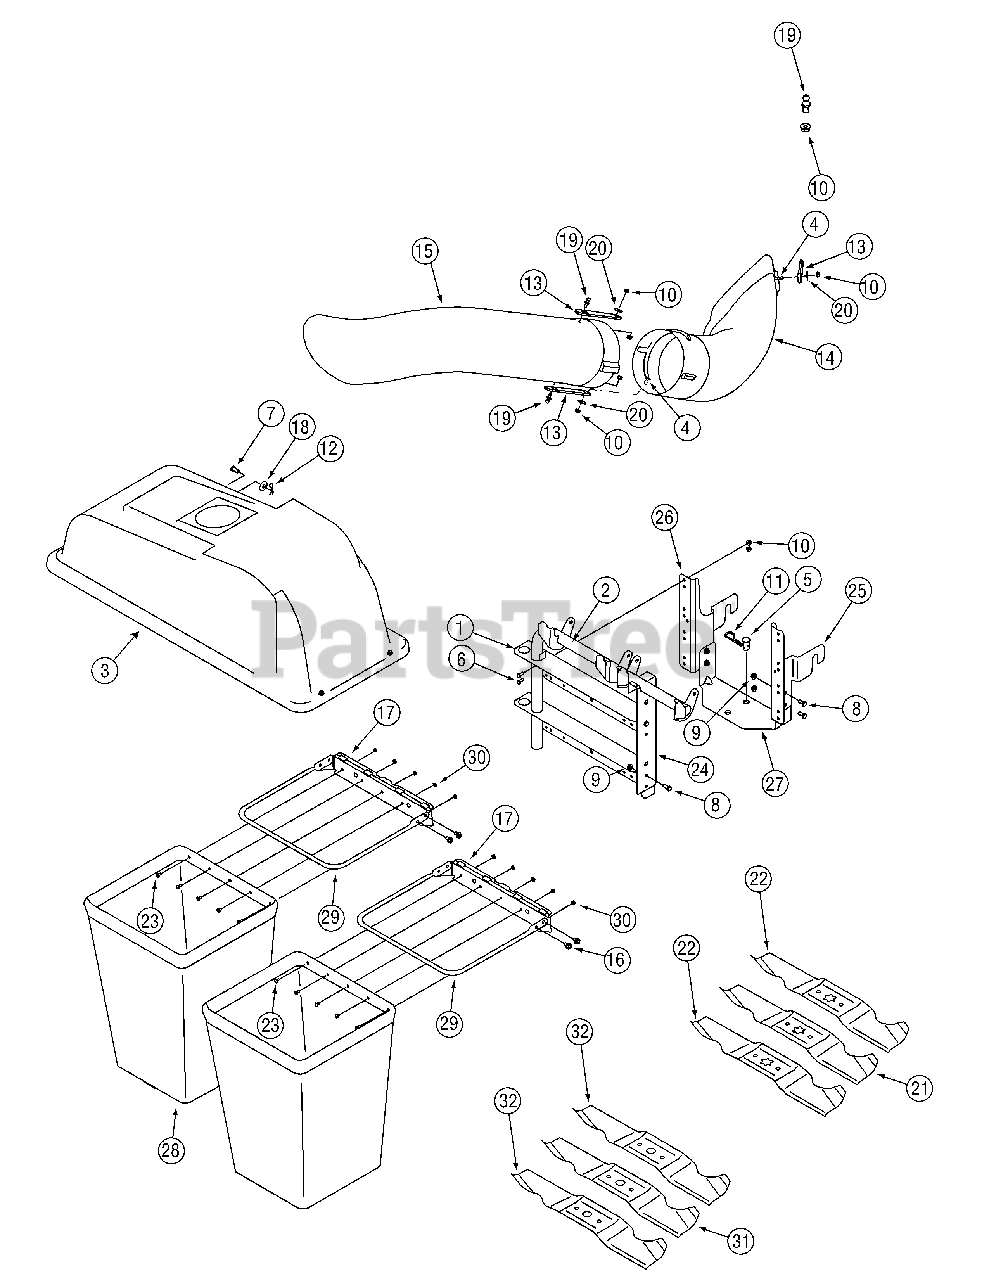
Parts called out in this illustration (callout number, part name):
3	Grass catcher Cover Assembly
4	Screw 1/4-20 x 1"
5	Clevis Pin
6	Hex Head Screw 1/4-20
7	Clevis Pin
8	Hex Screw 5/16-18 x 0.75"
9	Lock Nut 5/16-18
10	Hex Flange Lock Nut, 1/4-20
11	Hairpin Clip
12	Click Pin
13	Chute Strap
14	Discharge Chute 46"
15	Catcher Tube
16	Self-Tapping Screw 5/16-18
18	Bell Washer
19	Grass catcher Pin
20	Flat Washer
21	Blade 14.88" Lg. Star Hole
22	Blade 16.28" Lg. Star Hole
23	Machine Screw, , #10-24 x .5
28	Catcher Bag
30	Hex Sems Nut, #10-24
